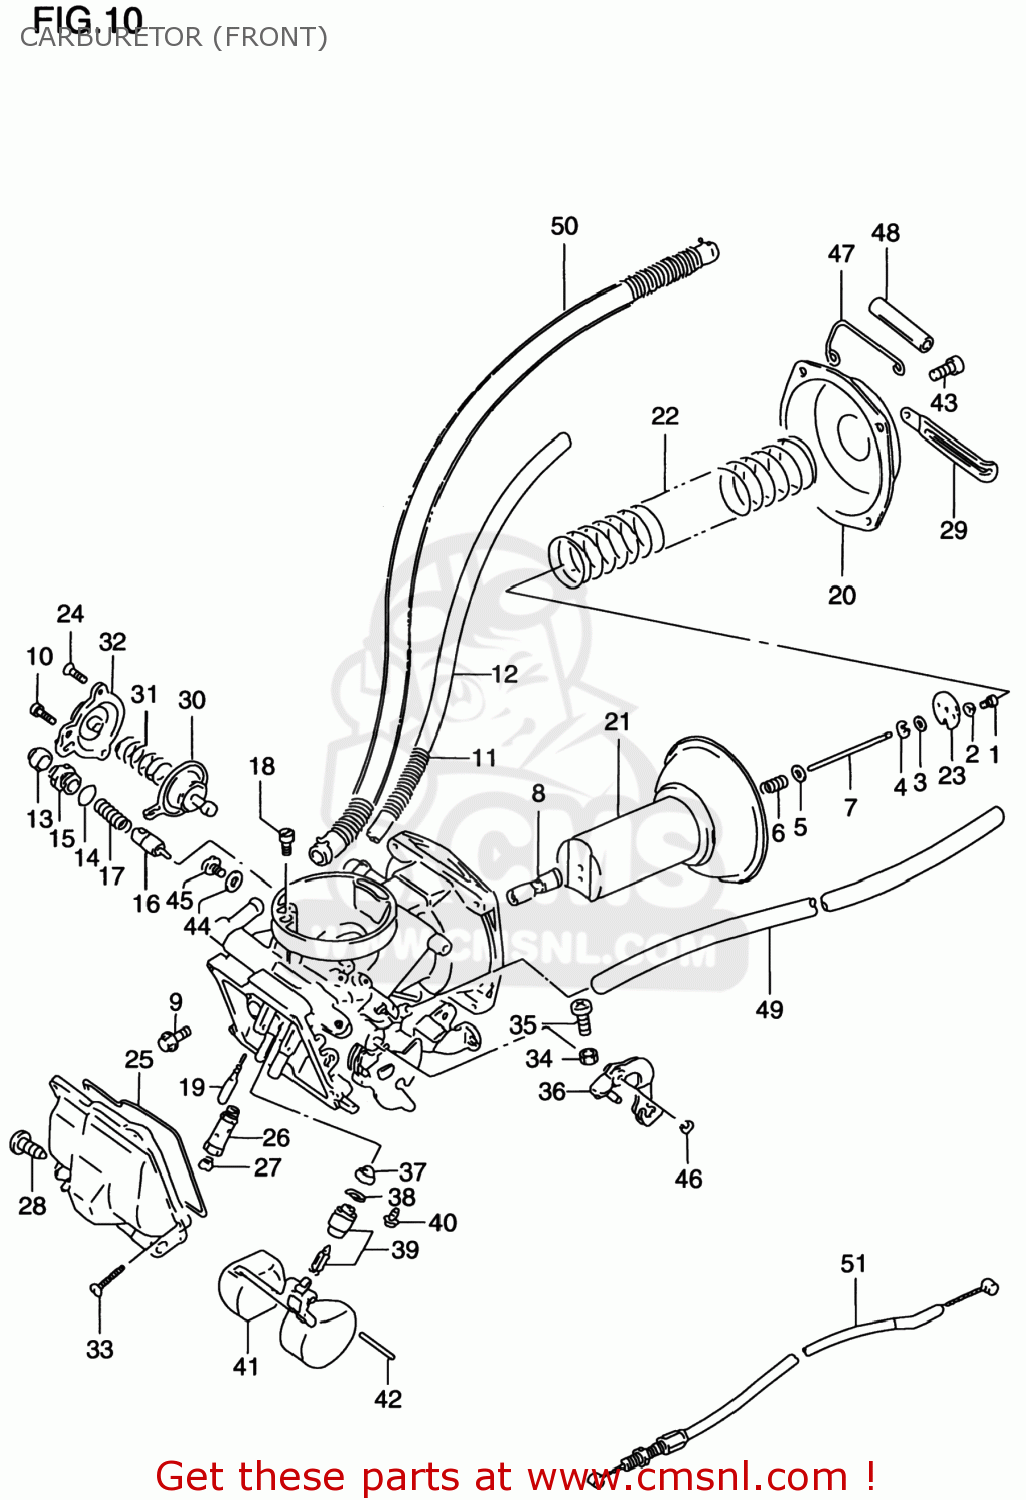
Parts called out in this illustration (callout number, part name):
1	SCREW
2	WASHER,LOCK
3	RING
4	CLIP
5	WASHER
6	SPRING
7	NEEDLE,JET
8	JET,NEEDLE(P-2M)
9	SCREW
10	SCREW
11	SPRING
12	HOSE(5X8.2X600)
13	CAP
14	O RING
15	HOLDER,GUIDE
16	PLUNGER,STARTER
17	SPRING
18	JET,AIR(65)
19	JET,PILOT(40)
20	COVER
21	DIAPHRAGM,CARBURETOR
22	SPRING,DIAPHRAGM
23	PLATE
24	SCREW,UPPER
25	O RING,FLOAT CHAMBER
26	HOLDER,MAIN JET
27	JET,MAIN(127.5)
28	SCREW,DRAIN
29	CLAMP(L:65)
30	DIAPHRAGM ASSY
31	SPRING
32	COVER
33	SCREW
34	NUT
35	SCREW
36	LEVER,ASSY
37	FILTER
38	O-RING,NEEDLE VALVE
39	VALVE ASSY,NEEDLE
40	SCREW
41	FLOAT
42	PIN,FLOAT
43	SCREW
44	GASKET,DRAIN PLUG (NAS)
45	SCREW
46	E RING
47	CLIP
48	HOSE(6X10X600)
49	(CA) HOSE SET,FUEL
50	HOSE ASSEMBLY
51	CABLE,IDLE SYNCRO
52	O RING,PILOT AIR SCREW
53	WASHER
54	SPRING
55	SCREW,PILOT
56	PLUG
